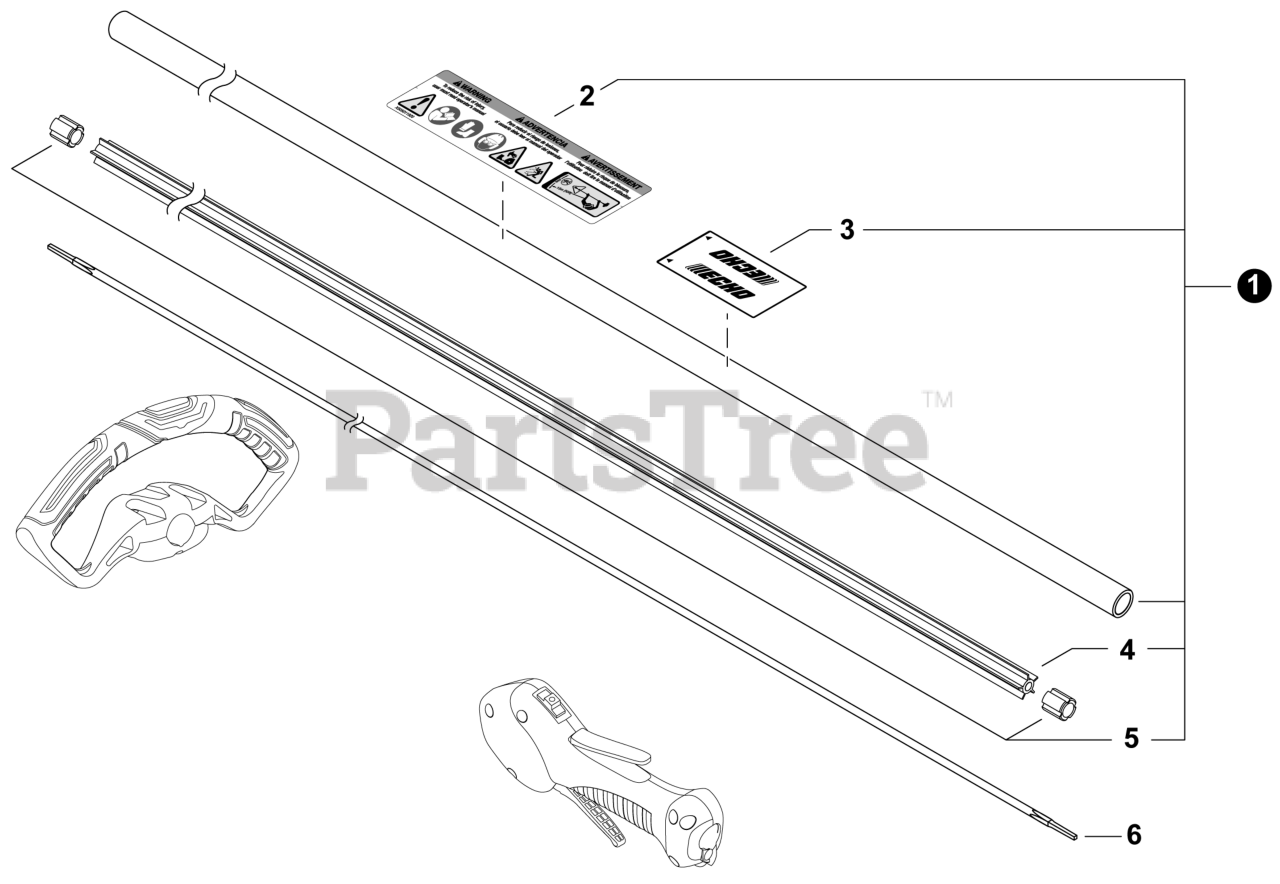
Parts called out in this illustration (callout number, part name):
1	MAIN PIPE ASSY
2	LABEL - CAUTION ISO
3	LABEL - HANDLE LOCATION
4	LINER, FLEXIBLE
5	STOPPER
6	DRIVESHAFT - FLEXIBLE
